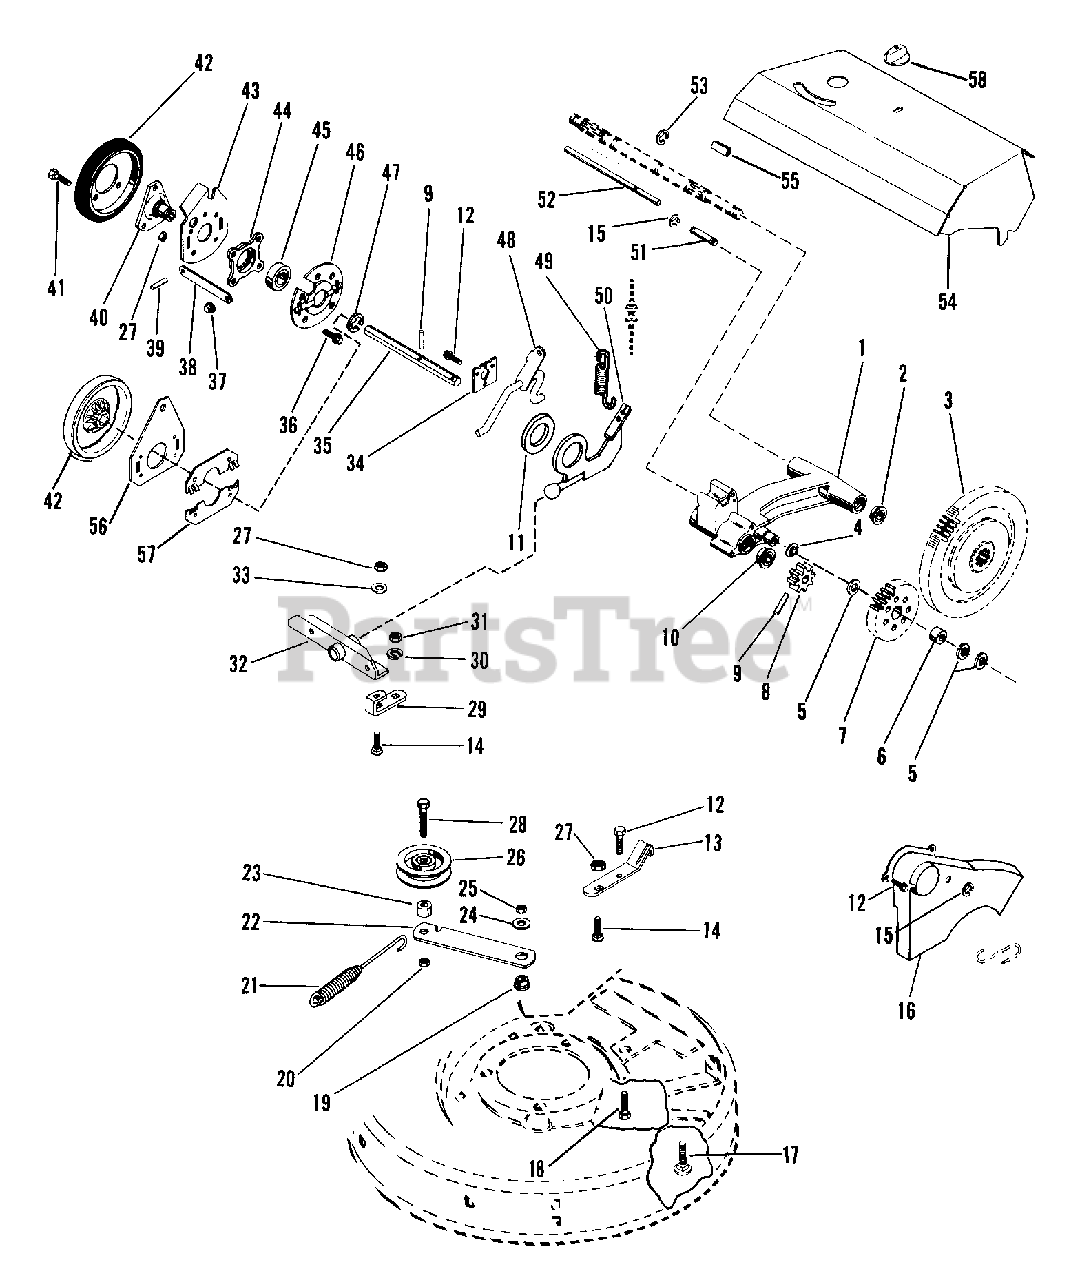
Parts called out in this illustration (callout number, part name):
1	DRIVE MOUNT
2	BRG-BALL .752X1.50X.45
2	BRG-BALL .625X1.383X.50
3	DIFFERENTIAL ASSEMBLY
4	RETAINER
5	WSHR-FL-STL .505X.880X.072 PL
6	BRG-BALL .500X1.38X.437
7	IDLER GEAR
9	PIN-ROLL .188X.88
10	BRG-BALL .562X1.375X.437
11	WSHR-FL-STL 1.390X2.00X.020 PL
12	SCR-TAP 12-24X.50 HWH PL TR
13	CABLE ANCHOR
14	BLT-RDHDSQNK .25-20X.50 SHT PL
15	RG-RTNG-EXT .438X.035
16	GEAR COVER
17	BLT-RDHDSQNK .312-18X.62SHTPL
18	BLT-HEX .31-18X.75 PL GR2
19	BSHG, FLG .325X.499X.26X.88
20	NUT-LK .437-14 GR A PL
21	SG-TENS .043X.44X3.31 WLD 5.8
22	IDLER ARM
23	SPACER .52 X .45 X .34
24	WSHR-FL-STL .323X.625X.062 PL
25	NUT-LK .312-18 GR A PL
26	IDLER-FLAT 1.75 X .47
27	NUT-LK-CTR .250-20 PL
28	BLT-HEX .44-14X1.25 PL GR2
29	BRACKET,ACTUATOR
30	WSHR-LK .312X.097 PL HVY
31	NUT-HEX .312-18
32	PIVOT CHANNEL WELDMENT
33	WSHR-FL-STL.344X.688X.065PL
34	RETAINER PLATE
35	HEX SHAFT
36	SCR-TAP 10-24X.375 HWH PL TR
36	TAPTITE M5-0.8X16MM H-FL-PL
37	PUSH NUT, .25
38	SHIFT LINK
39	PIN-ROLL .125X.63
39	PIN-ROLL .125X.50
40	FRICTION WHEEL HUB
41	BLT-HEX .25-20X.50 PL GR2
42	FRICTION DISC
42	FRICTION WHEEL ASSEMBLY
43	BEARING PLATE
44	BEARING RETAINER
45	BRG-BALL 1.0X2.0X.56
45	BRG-BALL 1.0X2.0X0188
46	BEARING RETAINER
47	RG-RTNG-EXT 1.00X.042
48	SHIFT ARM WELDMENT
49	SG-TENS .051X.60X2.25 WLD 7.0
50	DRIVE ACTUATOR WELDMENT
51	IDLER SHAFT
52	ROD - GUIDE
53	RG-RTNG-EXT .750X.042
53	RG-RTNG-EXT .625X.035
54	DRIVE COVER
55	TRIM BUMPER
56	GUIDE PLATE
57	THRUST PLATE
58	WING NUT
